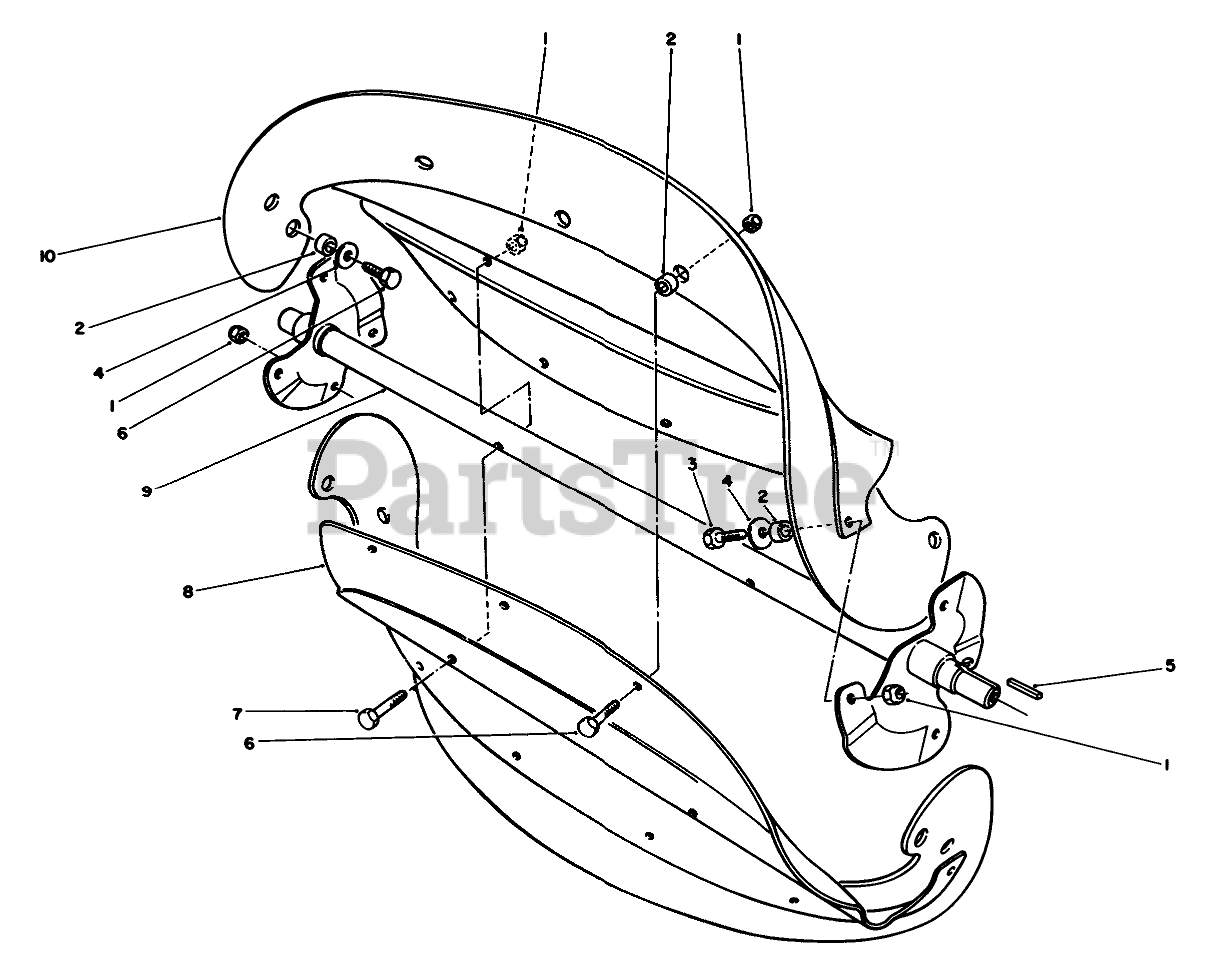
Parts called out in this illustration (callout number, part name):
1	NUT-LOCK, NI
2	SPACER-BLADE, ROTOR
3	SCREW-HH
4	WASHER-FLAT
5	KEY-SQUARE
6	SCREW-HH
7	SCREW-HH
8	ROTOR
9	ROTOR WA
10	Blade-Rotor
